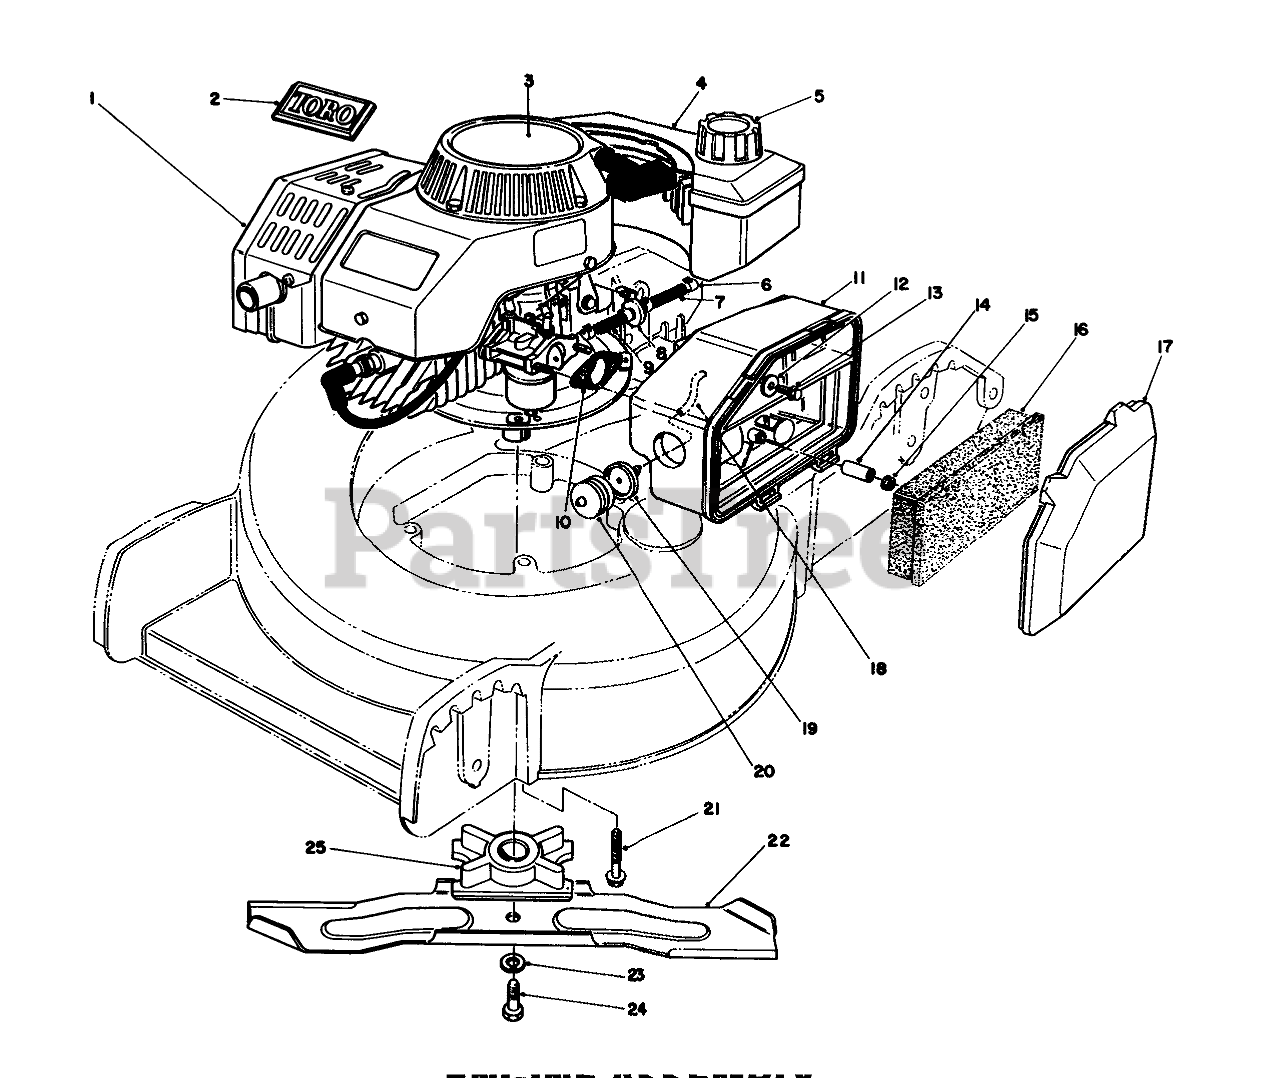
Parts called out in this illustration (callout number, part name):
1	Engine
2	TORO LOGO PLT
3	DECAL- 2 CYC RECOIL
4	Gas Tank Assembly
5	GAS CAP ASM
6	CLAMP-FUEL LINE
7	HOSE-FUEL
8	FILTER-FUEL
9	HOSE-FUEL
10	GASKET-AIR CLEANER
11	BODY-AIR CLEANER
12	WASHER-FLAT
13	SCREW-HH
14	SPACER
16	ELEMENT-AIR CLEANER
17	COVER-AIR CLEANER
18	HOSE-PRIMER
19	BODY-PRIMER
20	Bulb Primer
21	SCREW-HHF
22	Blade
23	WASHER-LOCK
24	SCREW-HH
25	BLADE RETAINER
